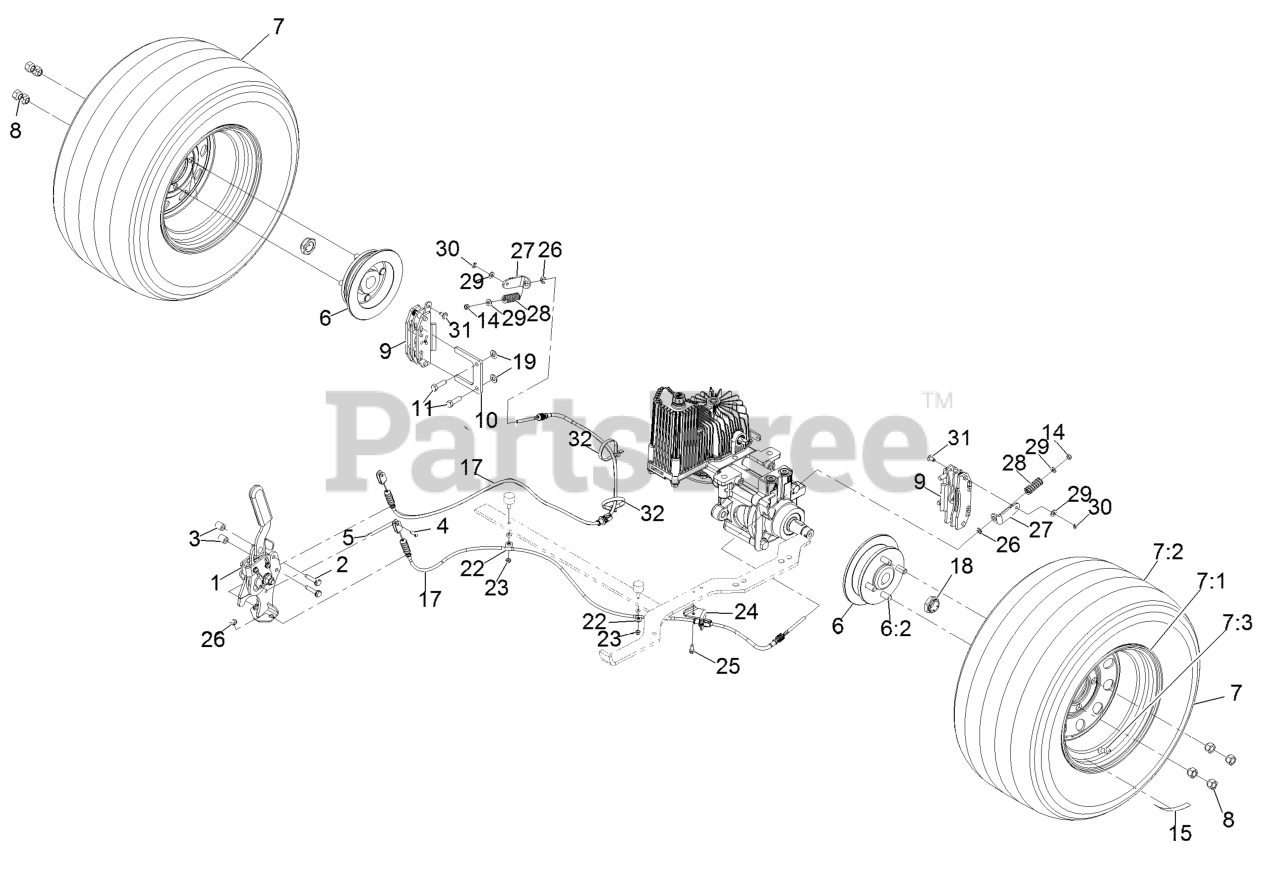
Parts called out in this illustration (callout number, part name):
1	BRAKE HANDLE ASM
4	PIN-CLEVIS
5	PIN-COTTER
6	WHEEL HUB ASM
6:2	STUD-WHEEL
7	WHEEL AND TIRE ASM
7:1	ASM, RIM
7:2	TIRE-DRIVE, 23X9.5-12
7:3	Stem-Valve
8	NUT-LUG
9	CALIPER-BRAKE
10	PLATE-MOUNT, BRAKE
11	SCREW-LOCK, PATCH
14	NUT-LOCK, NI
18	LOCKNUT
19	WASHER-FLAT
23	NUT-LOCK, NI
24	BRACKET-CABLE
25	SCREW-HWH
27	BRACKET-BRAKE, L
28	SPRING-DIE
29	WASHER-FLAT
31	PIN-BRAKE
32	TIE-CABLE
